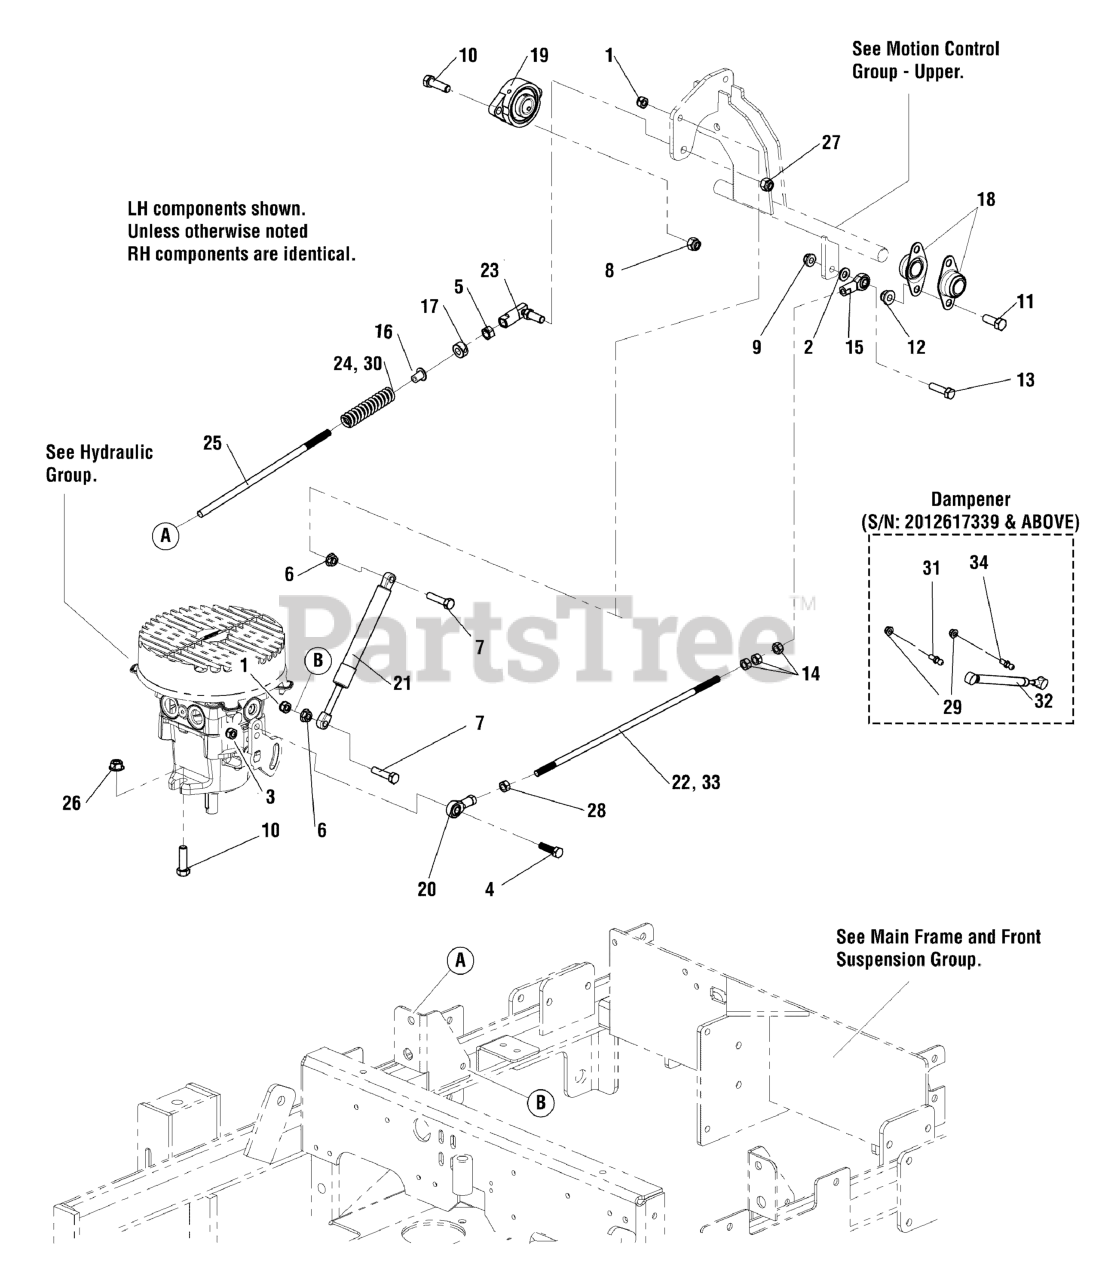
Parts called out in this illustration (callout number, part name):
1	NUT, M8-1.25 Hex Nylon Lock
2	WASHER, 5/16" SAE
3	NUT 5/16-18 HEX NYLON LOCK
4	BOLT, 5/16-18 X 1-1/8" GD5
5	NUT, HEX 3/8-24
6	NUT, M8-1.25 Hex Serrated Flange
7	BOLT, M8-1.25 x 35MM
8	NUT, 3/8-16 HEX NYLON LOCK
9	NUT, 5/16-18 HEX NYLON LOCK
10	BOLT, 3/8-16 X 1-1/4" GD5 CZ
11	BOLT, 3/8-16 X 1" GD5 CZ
12	NUT, 3/8-16 HEX NYLOCK FLANGE
13	BOLT, 5/16-18 X 1-1/4" GD5
14	NUT, HEX 5/16-24
15	BALL JOINT 5/16-24 RH FEMALE BRONZE RACE
16	BUSHING, FLANGE, .375 X .469 X 1.500
17	COLLAR, 3/8" SET
18	BEARING, BRONZE FLANGE, 3/4"
19	BEARING, FLANGE
20	BALL JOINT 5/16-24 LH FEMALE BRONZE RACE
21	KIT, DAMPENER CONVERSION IS3100Z
22	ROD, HYDRO LINKAGE 3000
23	BALL JOINT, 3/8-24 FEM. STUD.
24	SPRING, COMP. 1/2 ID X .140 WIRE X 3.25
25	ROD, NEUTRAL CONTROL
26	NUT, 3/8-16 HEX LG. SERR FLG
27	NUT, 3/8-24 HEX NYLON LOCK
28	NUT, 5/16-24 HEX, LH
29	NUT,5/16-18 HEX NYLOCK FLANGE
30	SPRING, REVERSE RETURN
31	BALL STUD, 5/16 X .75
32	DAMPENER, CONTROL
33	ROD, HYDRO LINKAGE 3000
34	BALL STUD, 5/16 X .50
